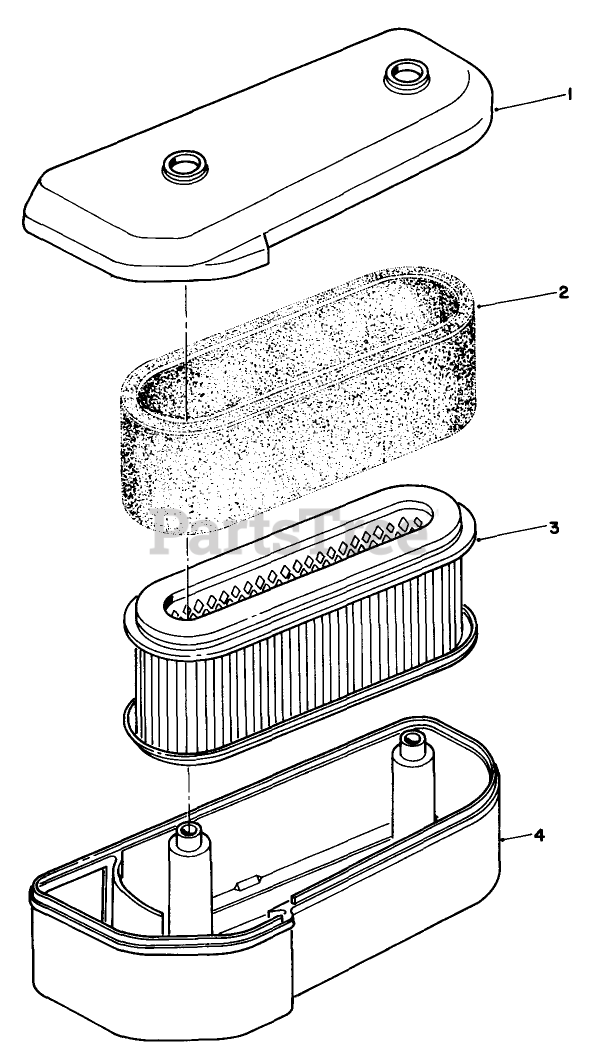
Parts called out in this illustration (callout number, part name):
1	CAP-Air Filter
2	Element
3	Element
4	CASE-Air Filter
